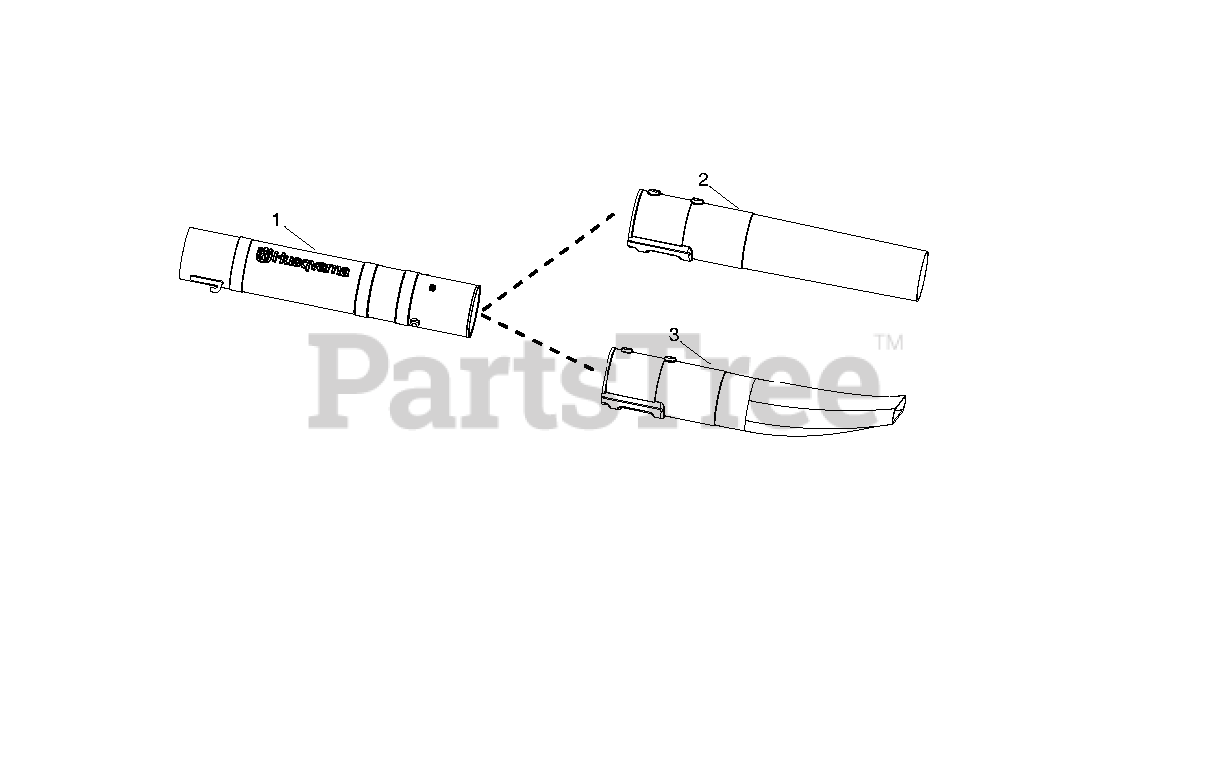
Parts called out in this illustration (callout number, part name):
1	ASSY TUBE BLOWER W/BARR
2	TUBE, LOWER
3	FLARE, LOWER TUBE
